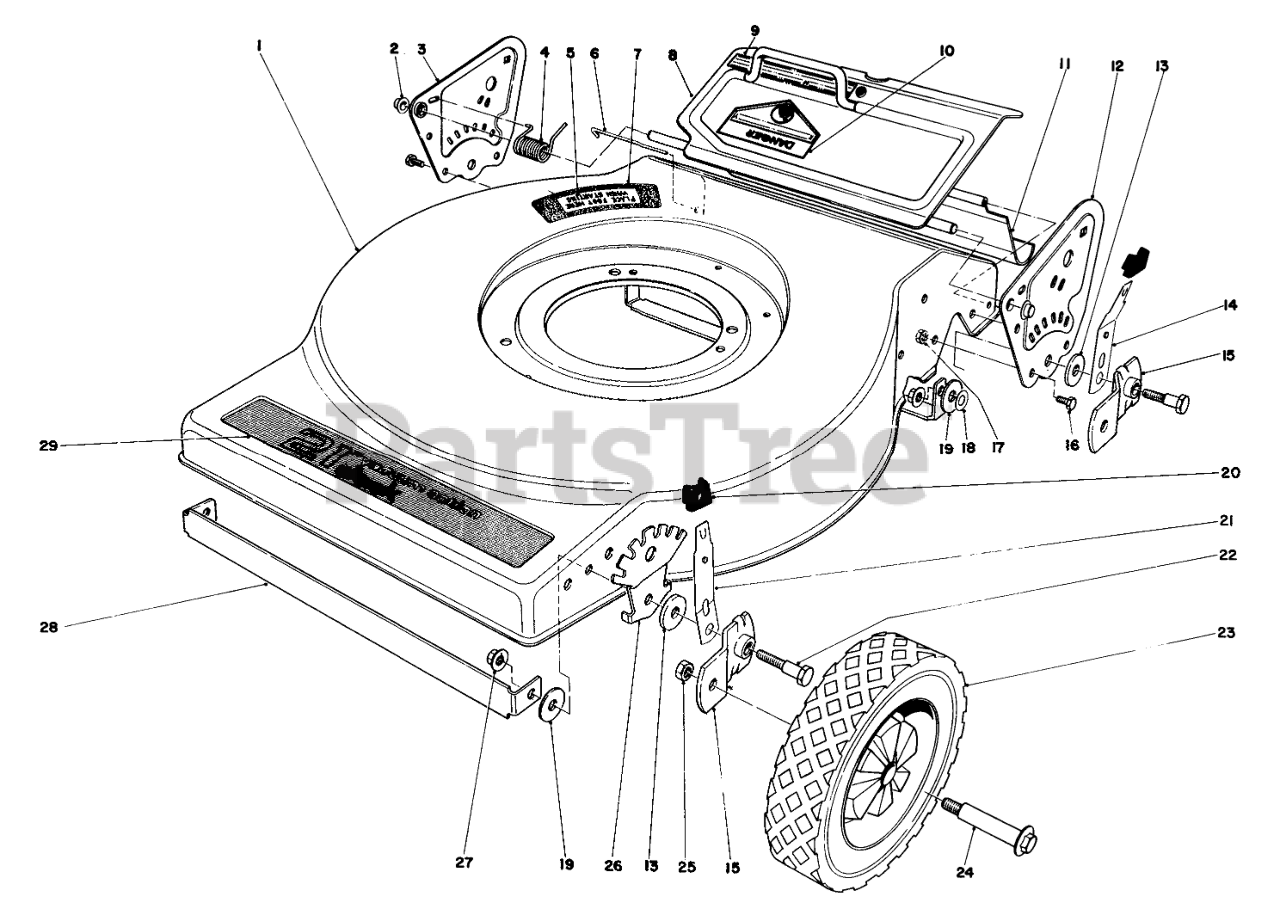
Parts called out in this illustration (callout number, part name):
1	Housing
2	RETAINER-PUSH ON
3	Side Plate R.H
4	TORSION SPRING
5	Decal Step Pad
6	SHIELD ROD
7	PAD STEP
8	Rear Door
9	Decal-Door
10	DECAL-DANGER
11	SAF SHIELD REAR
12	Side Plate L. H.
13	PIVOT WASHER
14	Spring Arm
15	PIVOT ARM ASM A
16	SCREW-HH
17	NUT-LOCK, CONE
18	WASHER-PLAIN
19	WASHER
20	KNOB-ARM
21	SPRING ARM ASM
22	Cup Spacer
23	Wheel & Tire Assembly
24	BOLT-WHEEL
25	Nut
26	WASHER-PLAIN
28	DECK SUPPORT
29	Decal-Deck
